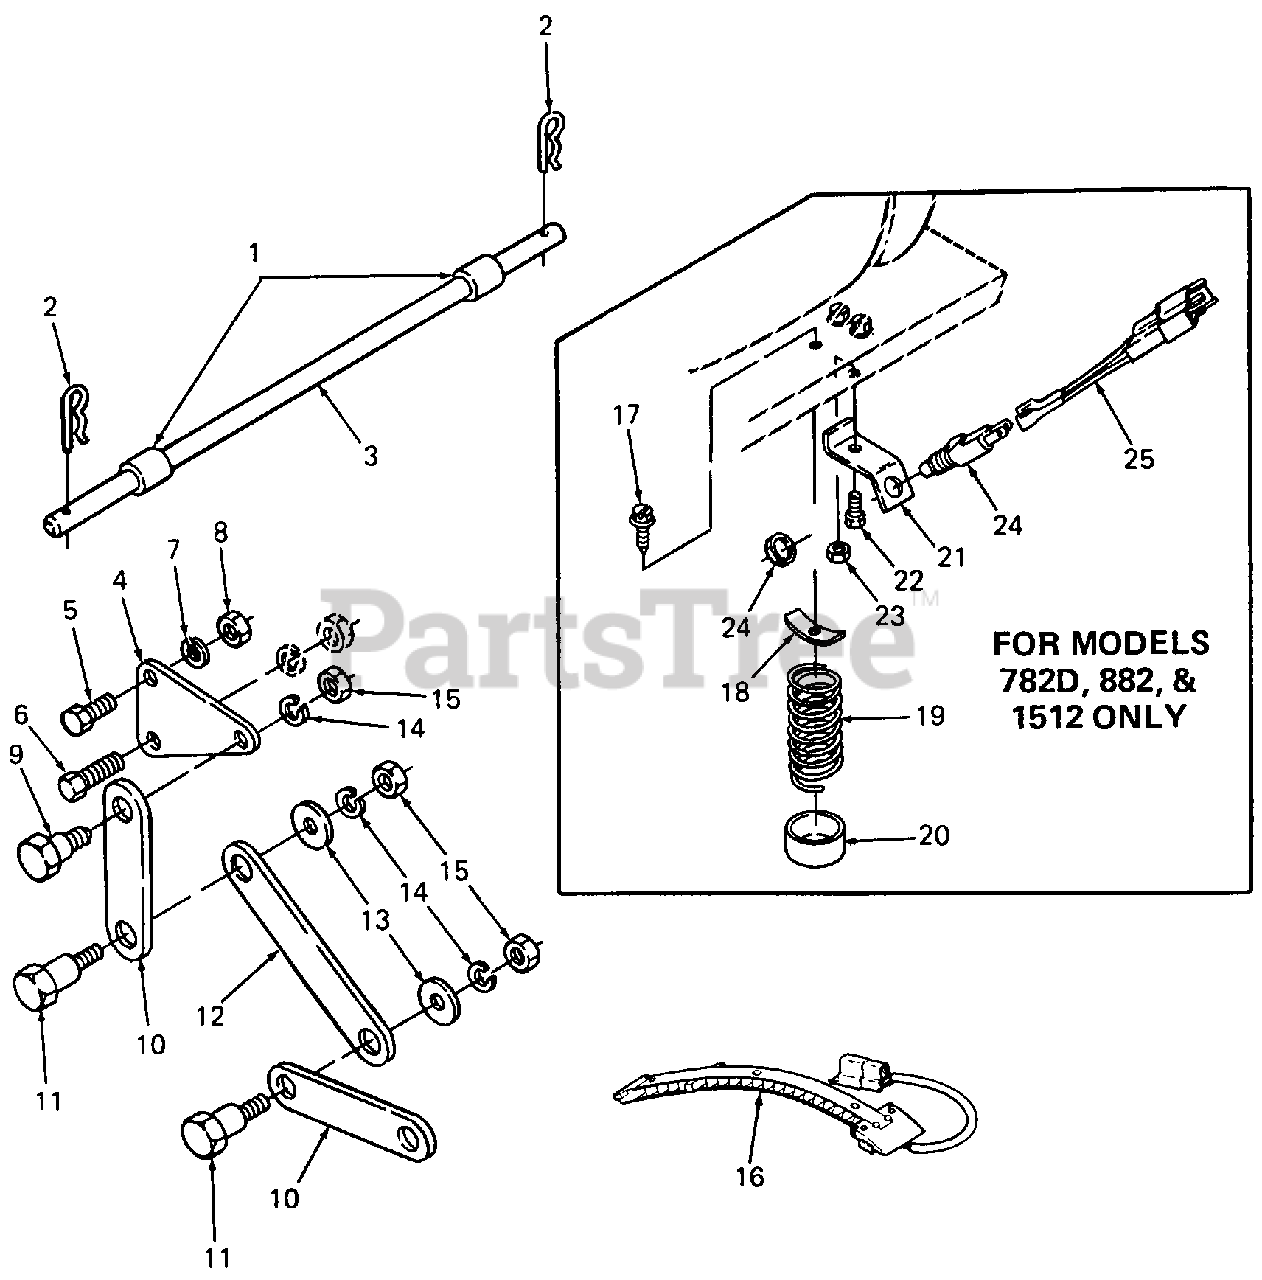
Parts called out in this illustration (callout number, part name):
1	Spacer, .688 ID X .88 OD X .88 L
2	Pin, Hitch Clip
3	Shaft, Tiller Mtg
4	Bracket, Tiller Mtg
5	Screw, Hex Cap, 5/16-18 X .75 Lg
6	Screw, Hex Cap, 1/4-20 X .88 Lg
7	Washer, Lock, 5/16
8	Nut, Hex, 5/16-18
9	Bolt, Shoulder
14	Washer, Lock, 3/8
15	Nut, Hex, 3/8-16
16	Switch Assy, NC Beam Seat
17	Screw, Hex Wash Hd AB Tapp, #10 X .50 Lg
18	Nut, Spring, #10 X 1.88 Lg
19	Spring, Compression
20	Cap, Spring
21	Bracket, Seat Switch
22	Screw, Hex Cap, 1/4-20 X .50 Lg
23	Nut, Hex Patch Lock, 1/4-20
24	Switch, Safety
25	Plug, Adapter
